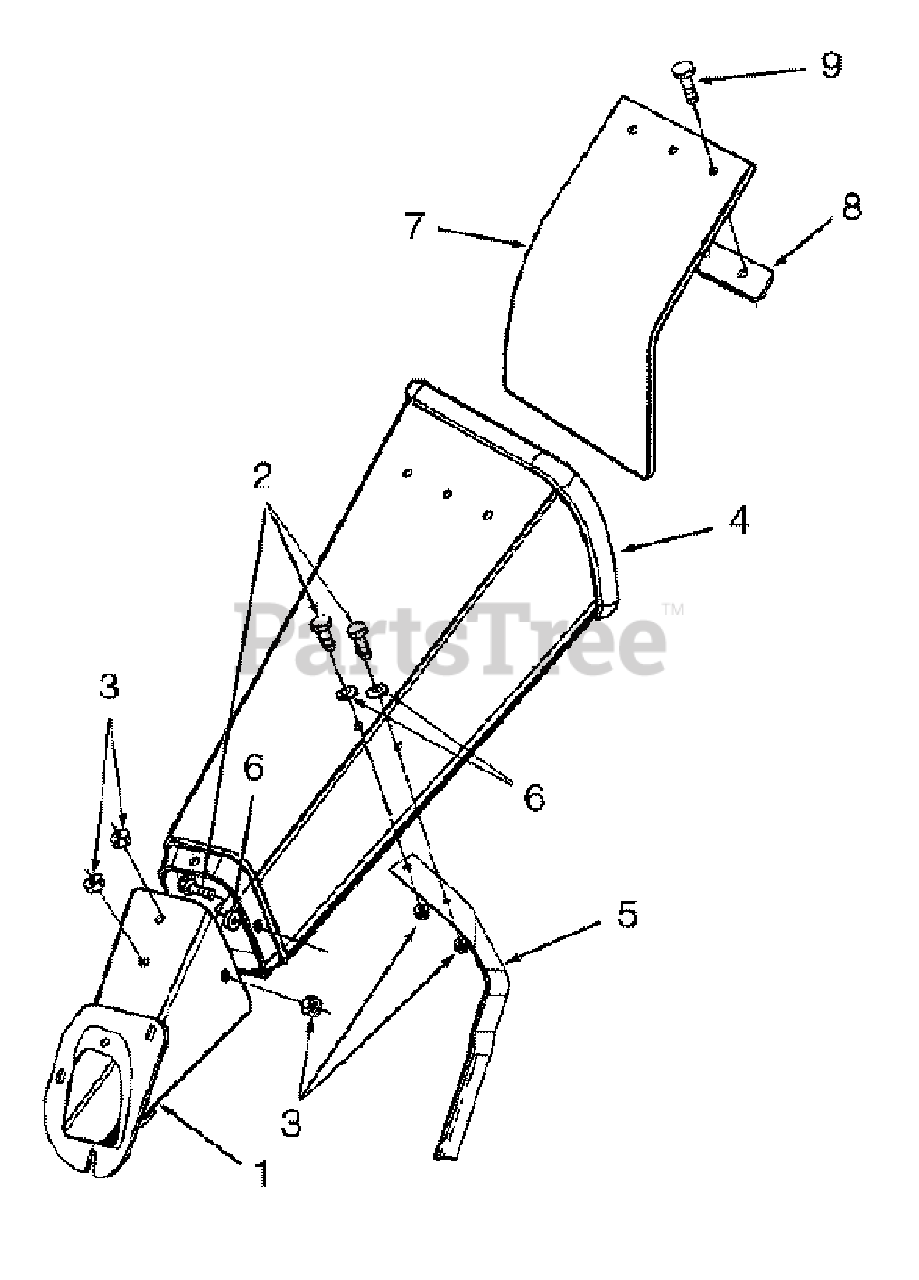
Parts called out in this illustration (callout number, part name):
1	Chute Assembly, Chipper
2	Screw, Hex Cap, 1/4-20 x .625
3	Nut, Hex Flange Lock, 1/4-20
4	Chute, Chipper (Grey)
5	Bracket, Chipper Chute Support
6	Washer, Flat, .28 x .74 x .63
7	Flap, Chipper Chute
8	Strip, Chute Flap
9	Rivet, Pop, .156 x .504
